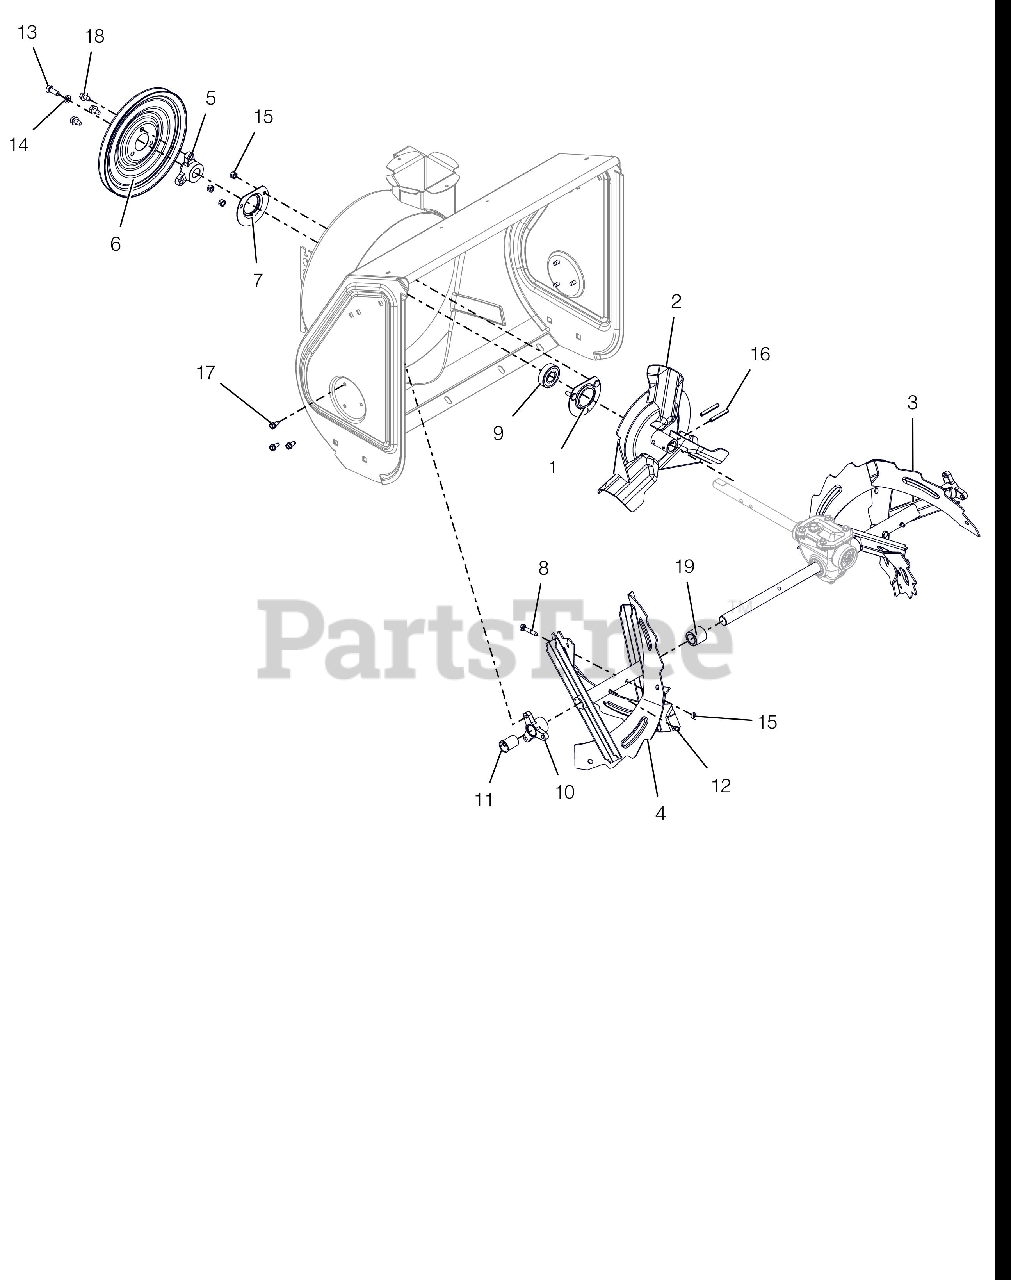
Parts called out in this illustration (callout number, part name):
1	BEARING FLANGE
2	IMPELLER, COMPACT 12" 3-BLADE
3	AUGER, LH 20", BLK SERR W/ZERK
4	AUGER, 20" RH, BLK SERR W/ZERK
5	PULLEY HUB, BOLT-ON D-BORE .75
6	PULLEY,SPIN FORM SINGLE GROOVE
7	BEARING FLANGE
8	SHEAR BOLT WITH NUT
9	BRG-BALL .750X1.750X.50
10	BUSHING, RAKE SHAFT .75"
11	BSHG-FLG SPLIT NYLINER .75"ID
12	ZERK,FITTING .25X.125 DRIVE IN
13	BLT-HEX .31-24X.75 YWZC GR5
14	WSHR-LK .312X.097 HVY YWZC
15	@NUT-LK-CTR .25-20 YWZC
16	PIN-ROLL .250X1.75
17	SCR-TAP .25-20X.50 HWH TR YWZ
18	@SCR-TAP .31-18X.50 HWH TR YWZ
19	BSHG-SLV .75X1.12X1.062 NYL BK
